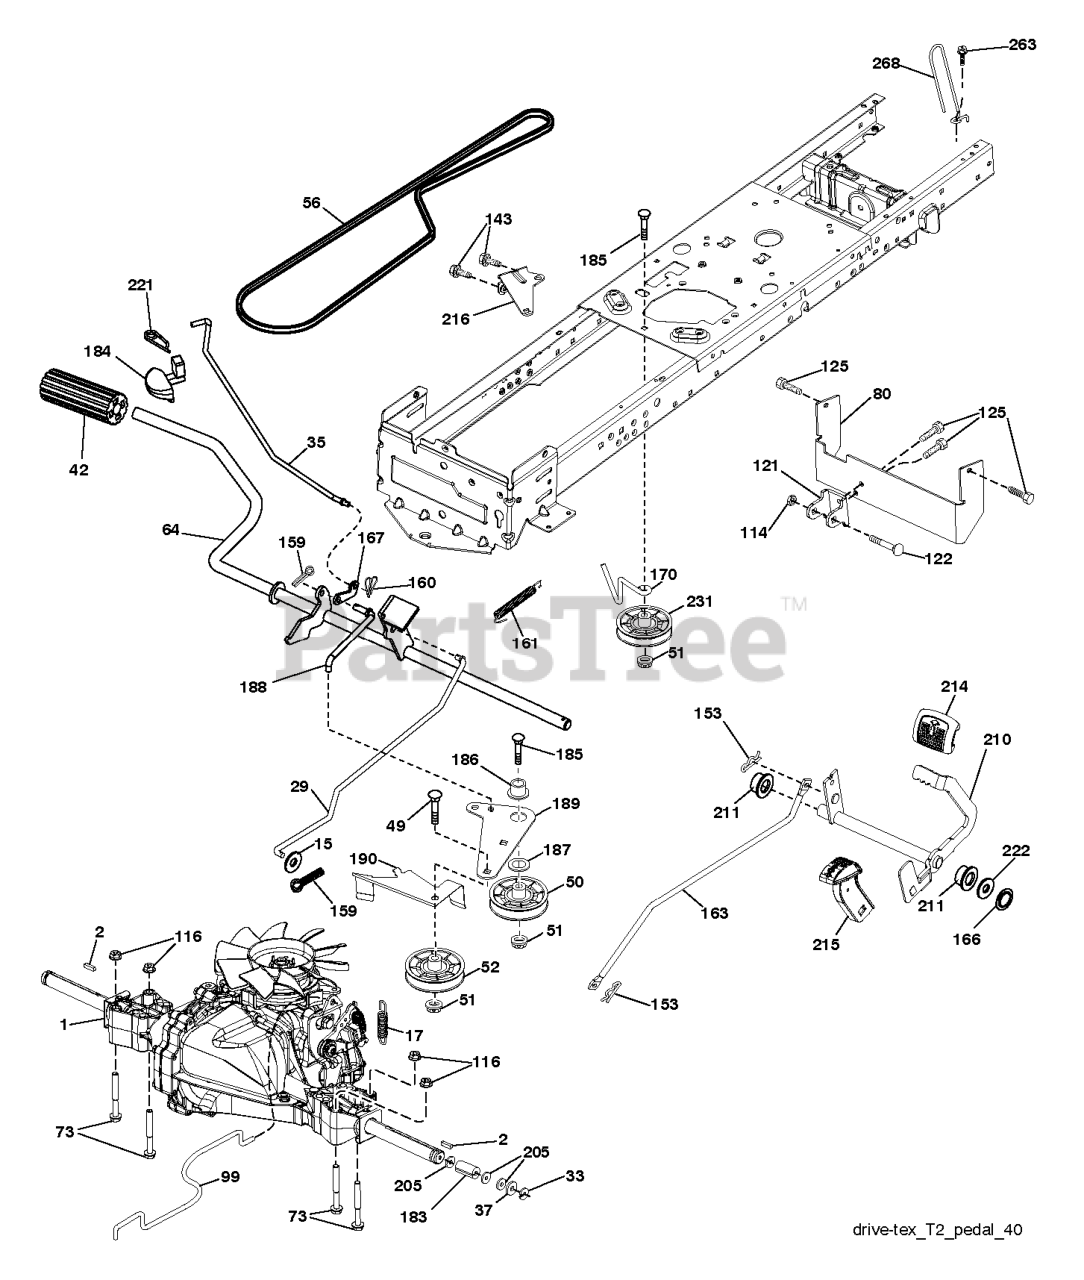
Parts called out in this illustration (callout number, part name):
2	SQUARE KEY
15	WASHER PLAIN WASHER 3/8 X 0.08
17	SPRING.BRAKE.HG3000/3500
29	ROD.BRAKE.T2.TEX
42	PEDAL COVER
50	IDLER.FLAT.910.OFFSET
51	NUT LOCK FLG 3/8-16 UNC
52	IDLER.V-GROOVE.910.OFFSET
56	BELT.DRIVE.T2.K66
64	SHAFT.ASM.PEDAL.BRK.CNTR
80	STRAP.TORQUE.T2
99	ROD.ASM.BYPASS.SPRING.T2.FS
121	BRACKET STRAP TORQUE
122	BOLT.5/16-18X2.5
125	SCREW
153	RETAINER M
160	GSPW Retainers
161	SPRING, RETURN LT
166	NUT.PUSH.625
167	LATCH.BRAKE.SPRING
170	KEEPER.CENTER SPAN.1.688
183	SPACER, AXLE PVST
184	HANDLE.PARKNG BRK.PRED.LT.428
186	SPACER.RETAINER
188	LINK.CLUTCH.GROUND DRIVE.LONG
189	BELLCRANK.GROUND.DRIVE.TEX.
190	KEEPER.BELLCRANK.DRIVE
210	ROCKER.ASM.PEDAL.CONTR
211	BEARING.NYLON
214	PEDAL.FORWARD.PAD.TEX
215	PEDAL.COVER.REVERSE.CRD.X428BK
216	BRACKET.PULLEY.IDLER.W/TEX
221	RETAINER.SPRING.CLIP.H
222	WASHER 21/32 X 1-1/4 X 10 GA.
231	IDLER.V-GROOVE.1.688.OFFSET
263	SCREW, 3/8-16X3/4
